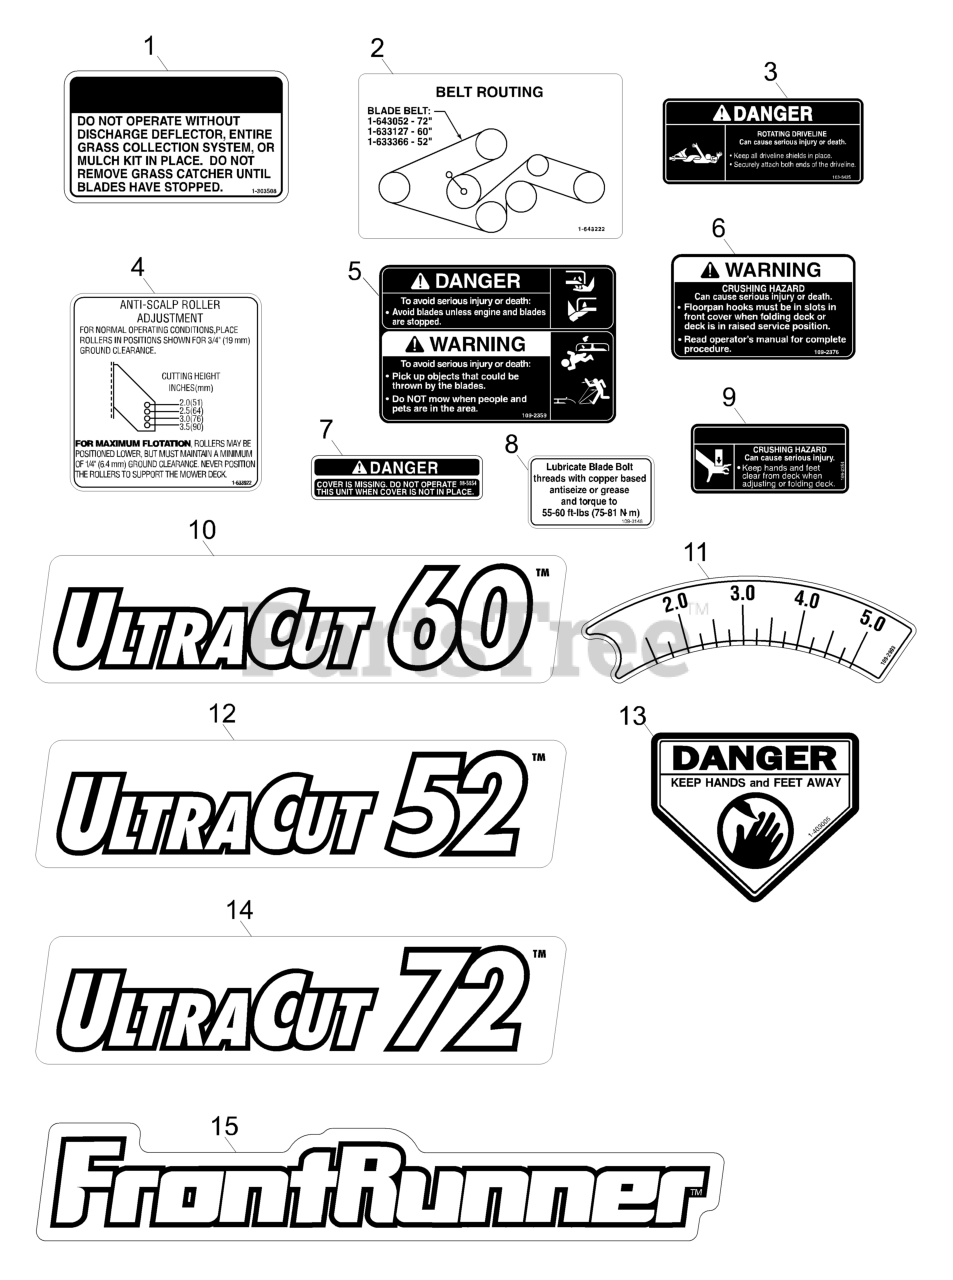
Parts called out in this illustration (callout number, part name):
1	DECAL-WARNING, DISCHARGE
2	DECAL,BELT ROUTING
3	DECAL-DRIVELINE
4	DECAL,ANTISCALP
5	DECAL,DECK WARNING
6	DECAL,CRUSHING HAZARD
7	DECAL-COVER, MISSING
8	DECAL,BOLT TORQUE
9	DECAL,CRUSHING HAZARD
10	DECAL,ULTRACUT 60
11	DECAL,DECK HEIGHT
12	DECAL,ULTRACUT 52
13	DECAL-DANGER
14	DECAL,ULTRACUT 72
15	DECAL,FRONTRUNNER
